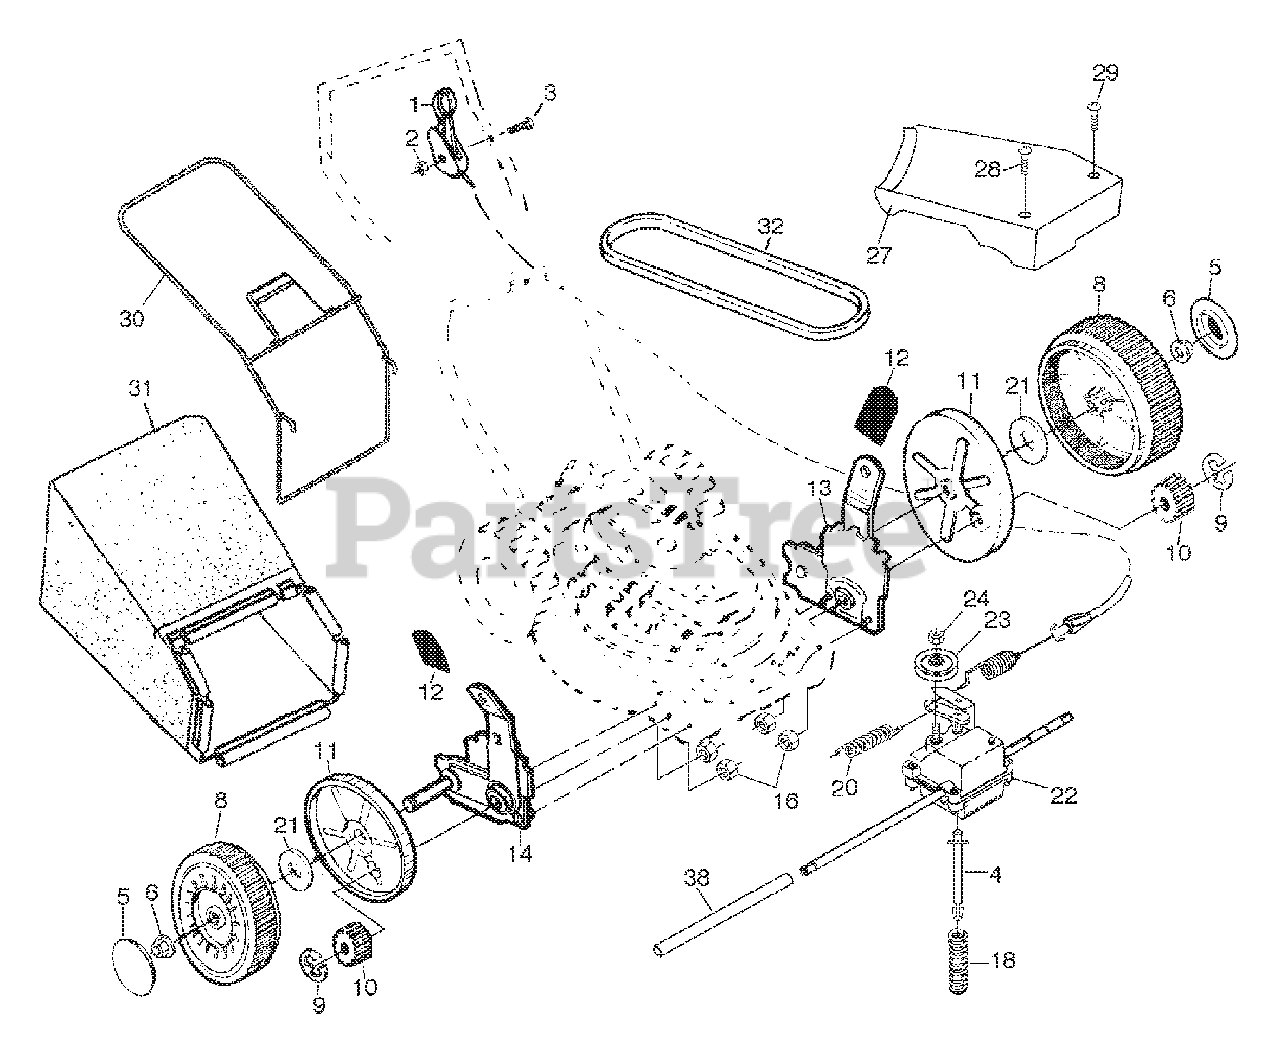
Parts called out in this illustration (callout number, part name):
1	Drive Control
2	Locknut #10-24
3	Pan Head Machine Screw 1/4-20 x 2-1/8
4	Spring Retainer
6	Nut
8	Wheel & Tire Assembly
11	Dust Cover
12	Selector Knob
13	Wheel Adjuster Assembly (Left)
14	Wheel Adjuster Assembly (Right)
16	Locknut
21	Washer 1/2 x 1-1/2 x .134
22	Gear Case Assembly
23	Drive Pulley
24	Locknut
27	Drive Cover
29	Pan Head Tapping Screw #10-24 x 1-3/4
30	Catcher Frame
31	Grass Bag
32	V-Belt
38	Drive Shaft Cover
